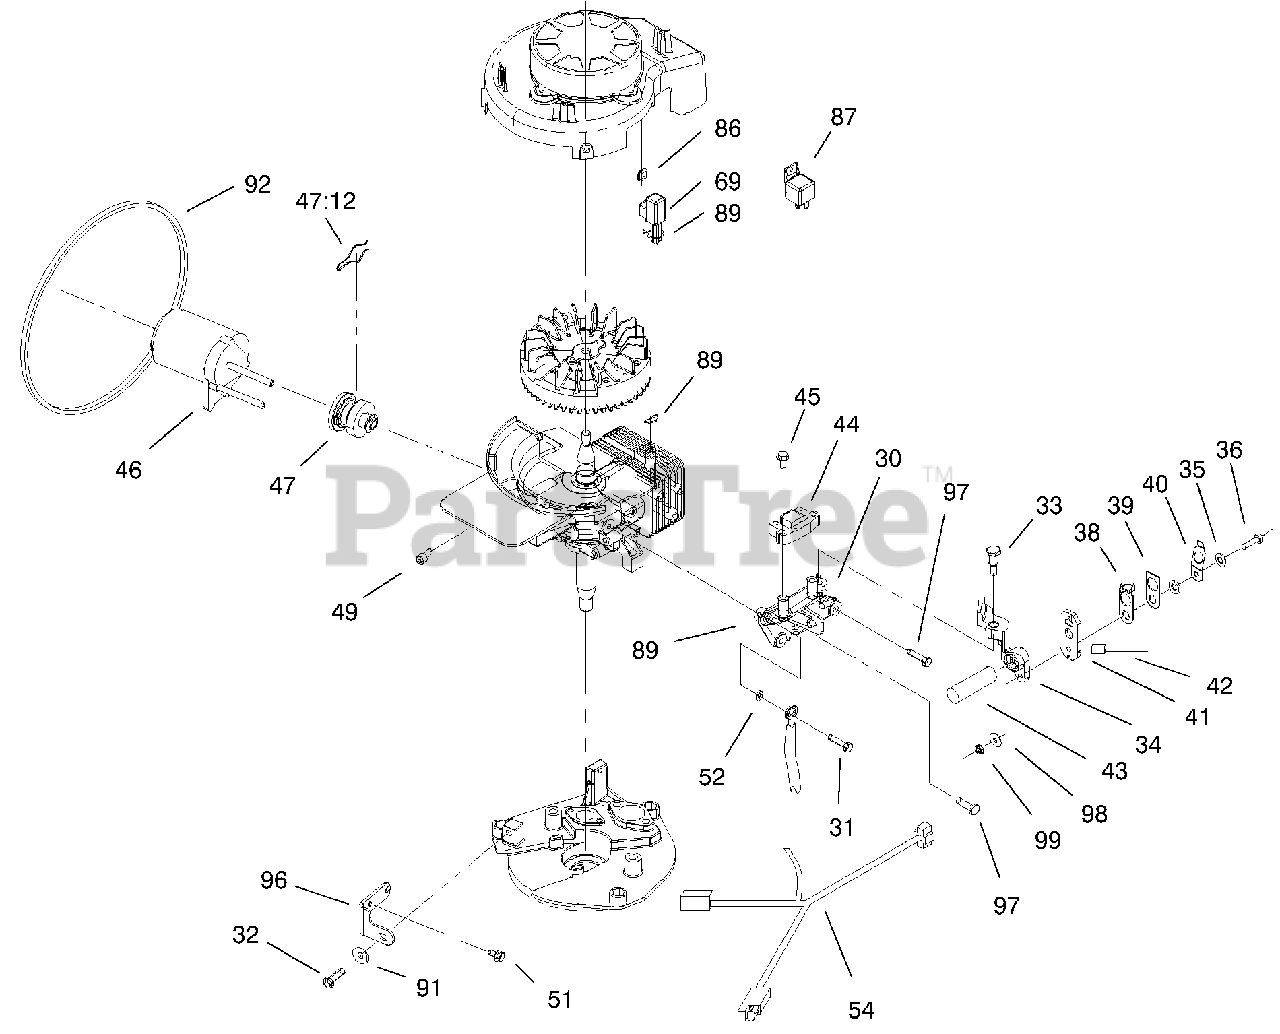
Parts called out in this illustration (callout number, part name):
30	BRKT ALT/BRAKE E
31	SCREW-HH
32	SCREW-HHF
34	BRAKE ASM E
35	WASHER
36	SCREW-HH
38	PLATE-CONTACT
40	SPRING-CONTACT
41	CASE ASM
42	WIRE-LEAD
43	SPRING-BRAKE
44	ALTERNATOR ASM
46	STARTER ASM
47	PINION ASM
47:12	SPRING - DRAG
49	SCREW-HSH
51	SCREW-HH
52	WASHER-LOCK
54	HARNESS-WIRE E
69	RECTIFIER
86	CLIP-MOUNTING
89	STRAP-TIE
91	WASHER - FLAT E
92	TIE-CABLE
97	SCREW-HH
98	WASHER-LOCK/EXT
99	LOCKNUT E
